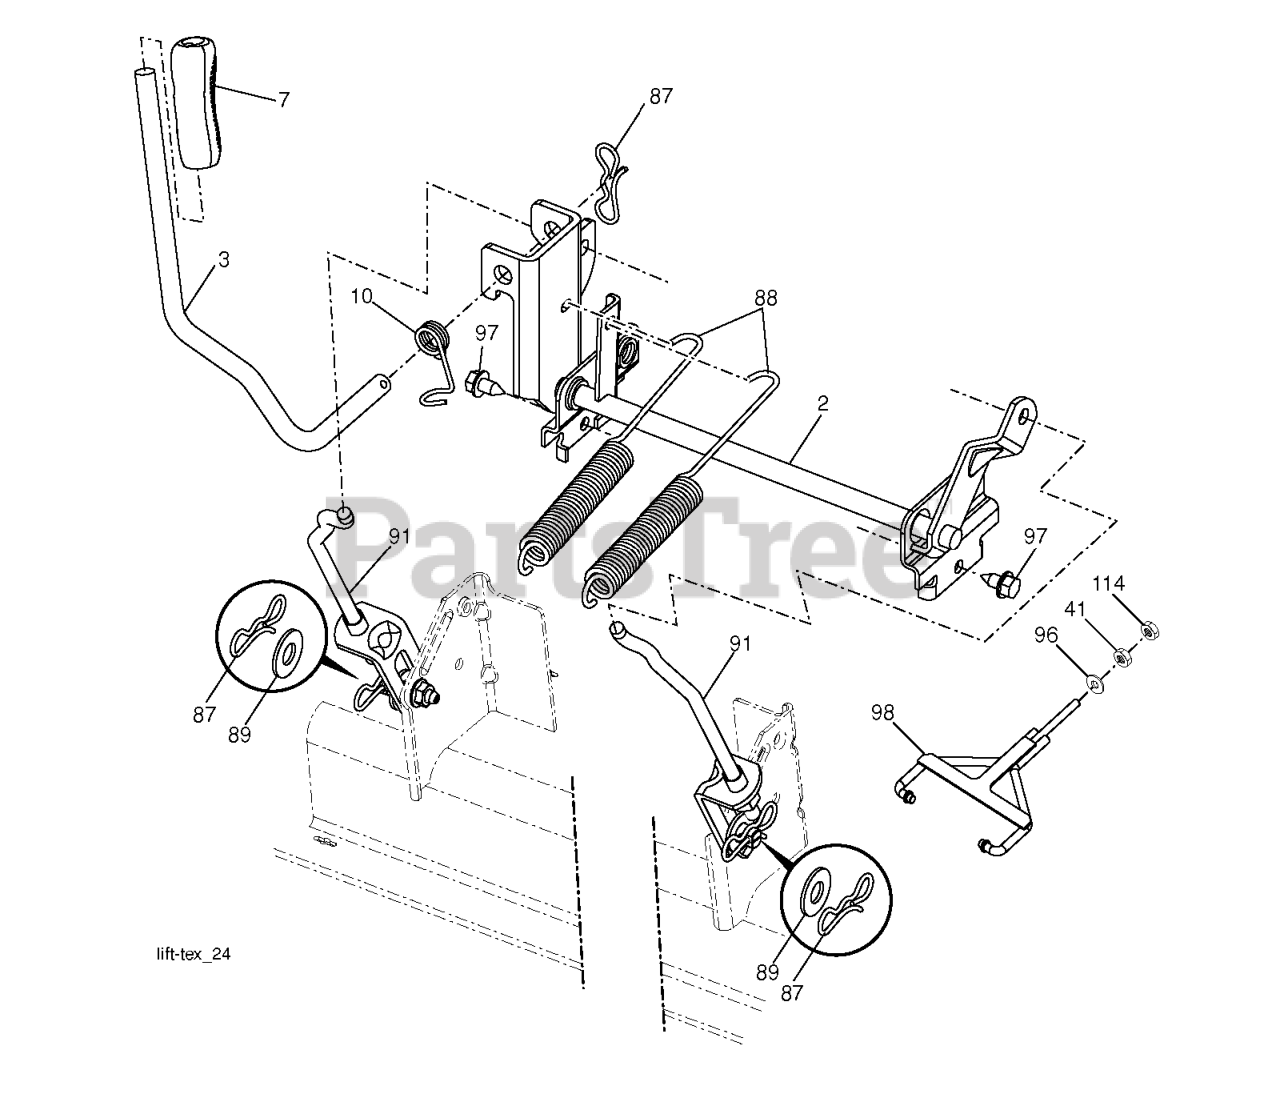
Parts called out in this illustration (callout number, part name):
2	SHAFT.ASM.CROSS.LIFT
3	LEVER.LIFT.HANDLE.GT
7	GRIP.HANDLE.LIFT.PVC.BLACK
10	SPRING.TORSION.LIFT.HANDLE
41	NUT, LIFT LINK 7/16-20
87	PIN.COTTER.7/16.BOW TI.
88	SPRING.LIFT.ASSIST.GT2
89	WASHER.CLEAR.ZINC
91	LINK.LIFT.ASM.REAR.GT.
96	BUSHING SPHERICAL SUSP. FRONT
97	SCREW, 3/8-16X3/4
98	SUSPENSION WLDT FRONT DECK
114	NUT **
